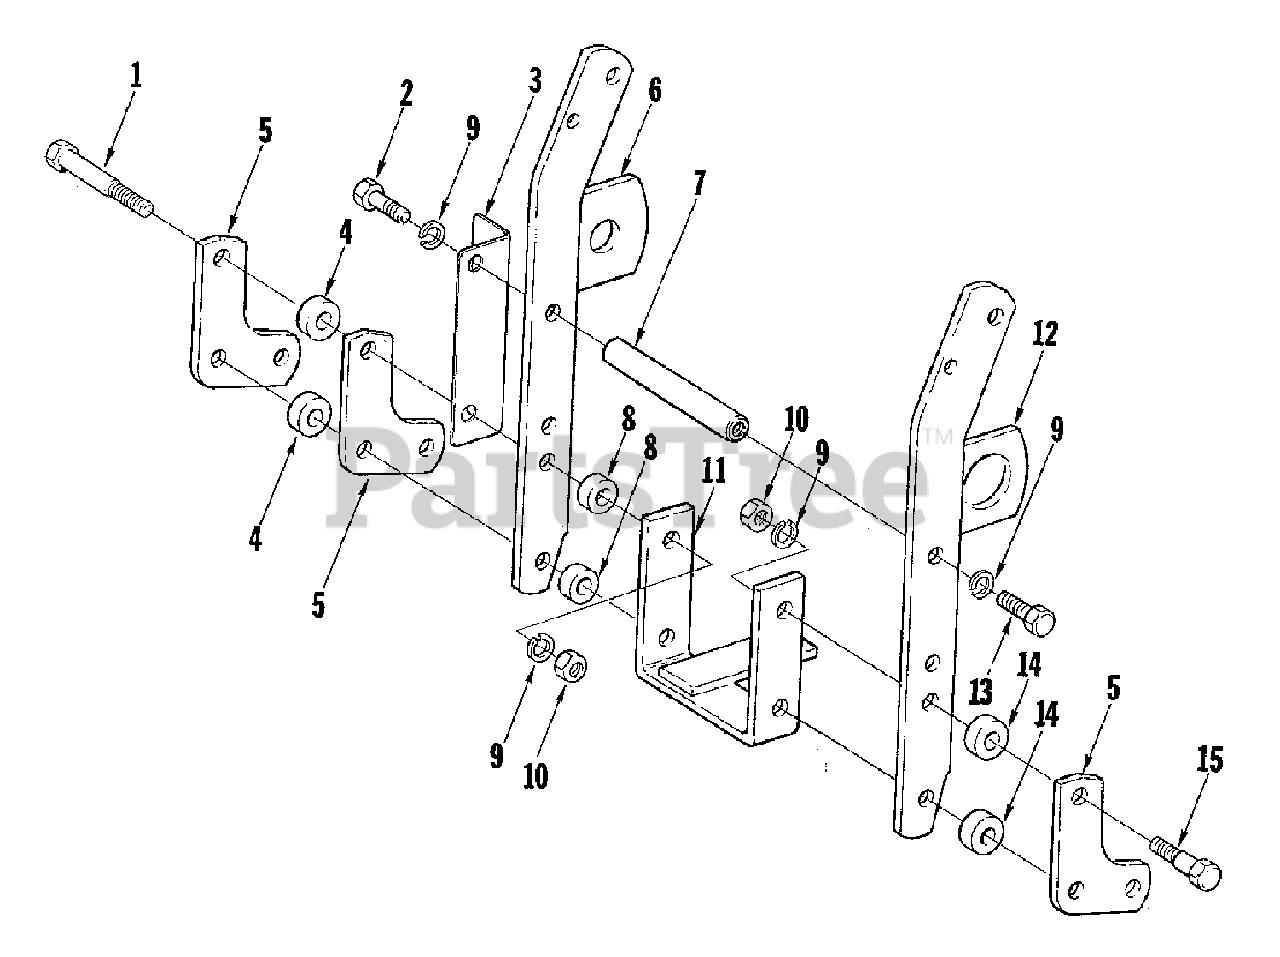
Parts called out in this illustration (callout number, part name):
1	SCREW, Hex Head Cap, 7/16-14 x 3
2	SCREW, Hex Head Cap, 7/16-14 x 1-3/4
3	PLATE, Decal
6	BAR ASSEMBLY, Upright
9	WASHER, Lock, 7/16
10	NUT, Hex, 7/16-14
11	DRAWBAR ASSEMBLY
12	BAR ASSEMBLY, Upright
13	SCREW, Hex Head Cap, 5/16-14 x 1-1/4
15	SCREW, Hex Head Cap, 7/16-14 x 2-1/4
